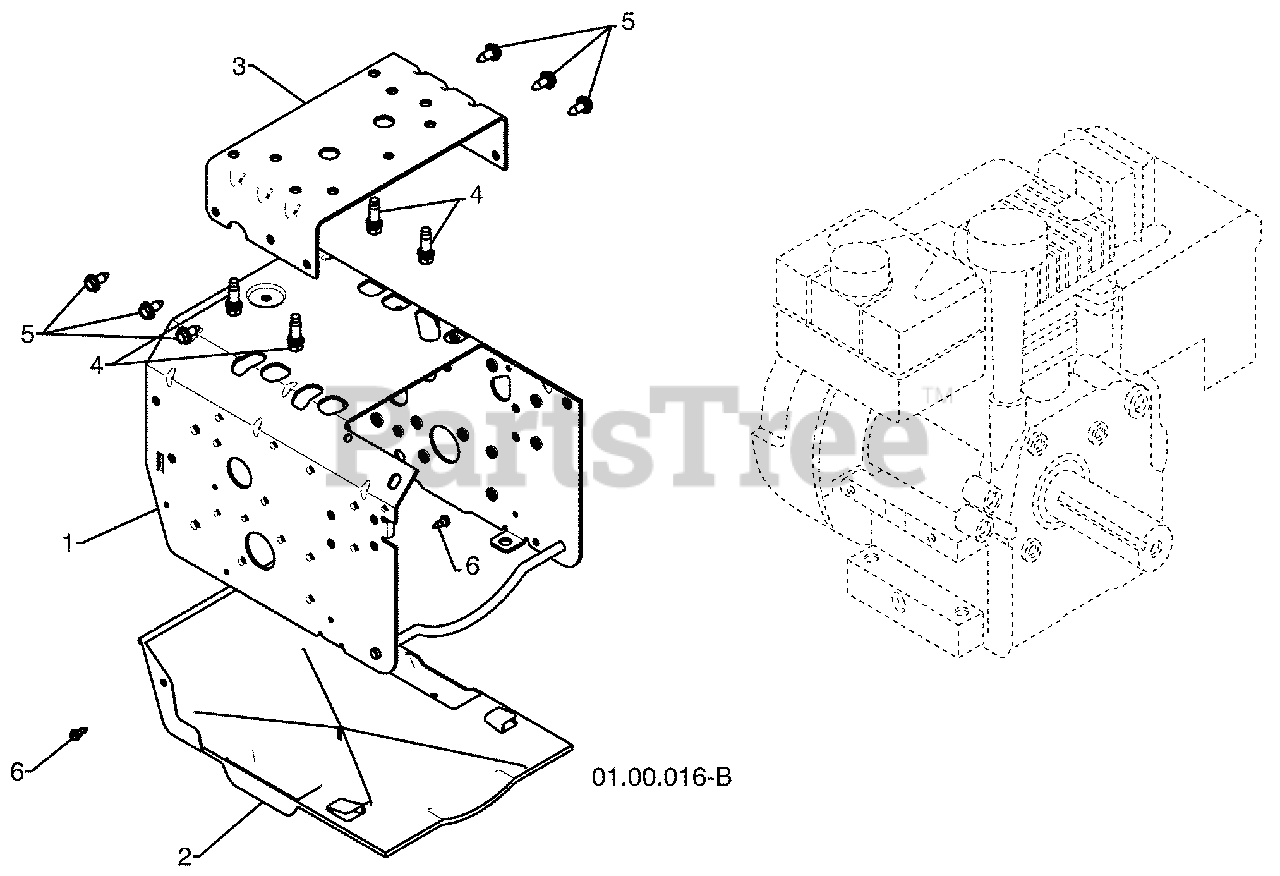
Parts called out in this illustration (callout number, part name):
2	BOTTOM PAN
3	ENGINE MOUNT PLATE
4	BOLT 3/8-16
5	SCREW 5/16-18 X .750
6	SCREW 10-24 X .625
